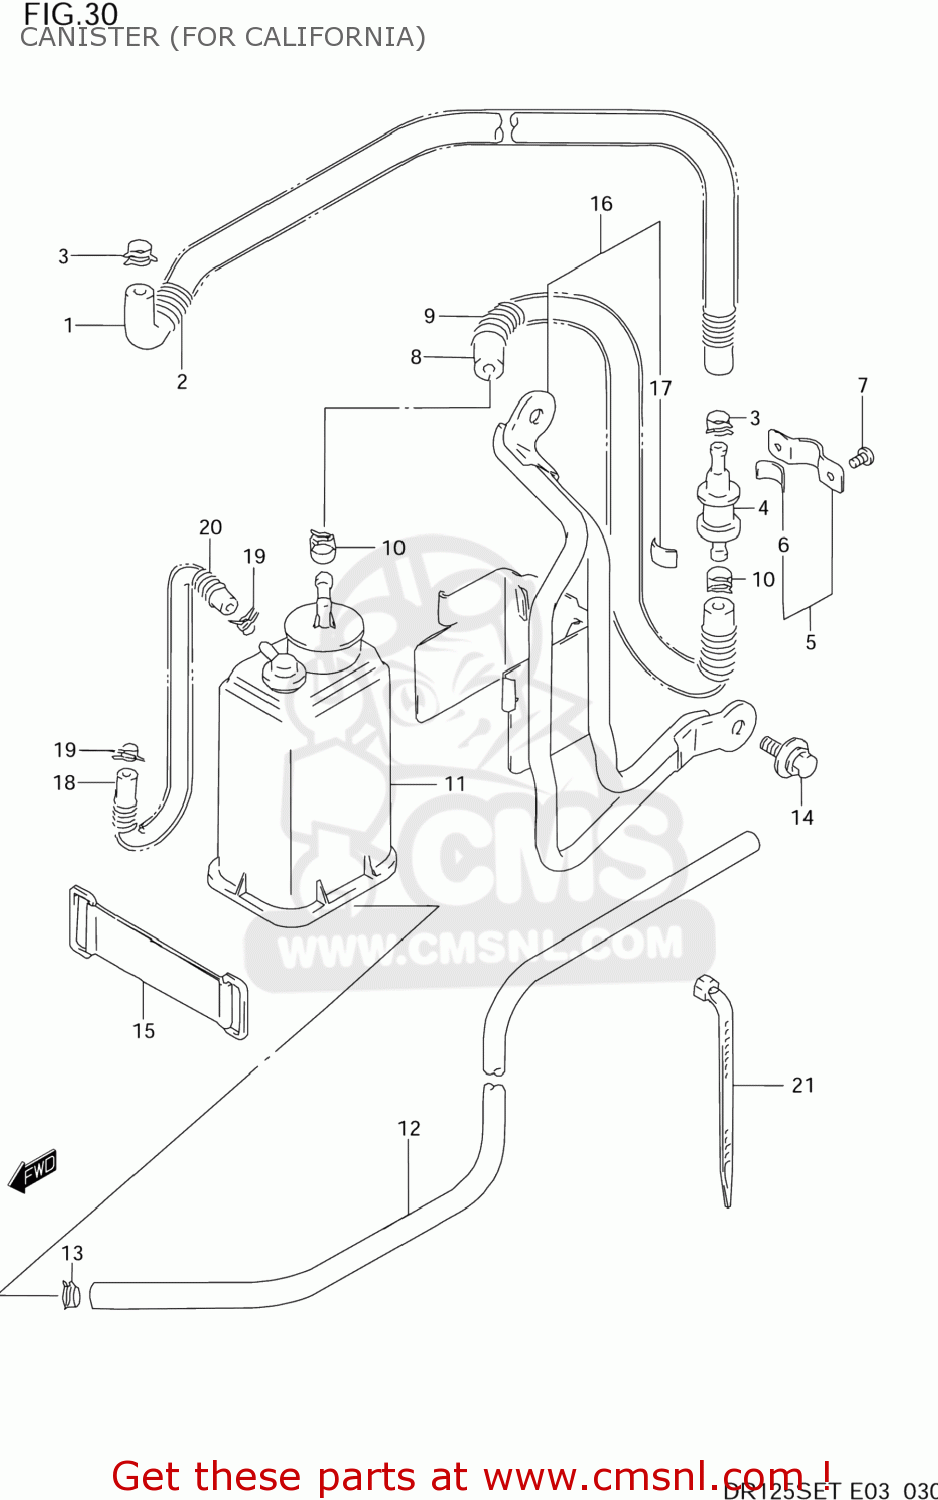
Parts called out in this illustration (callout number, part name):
1	HOSE (5.4X11.4X790)
2	SPRING
3	CLIP
4	VALVE,FUEL TANK BREATHER
5	PLATE,FUEL TANK BREATHER NO.2
6	CUSHION
7	SCREW
8	HOSE
9	SPRING
10	CLIP
11	CANISTER ASSY,CHARCOAL
12	HOSE(7X11X2000)
13	CLIP
14	BOLT
15	BAND
16	PLATE,CANISTER
17	CUSHION
18	HOSE
19	CLIP
20	SPRING
21	CLAMP(L:125)
